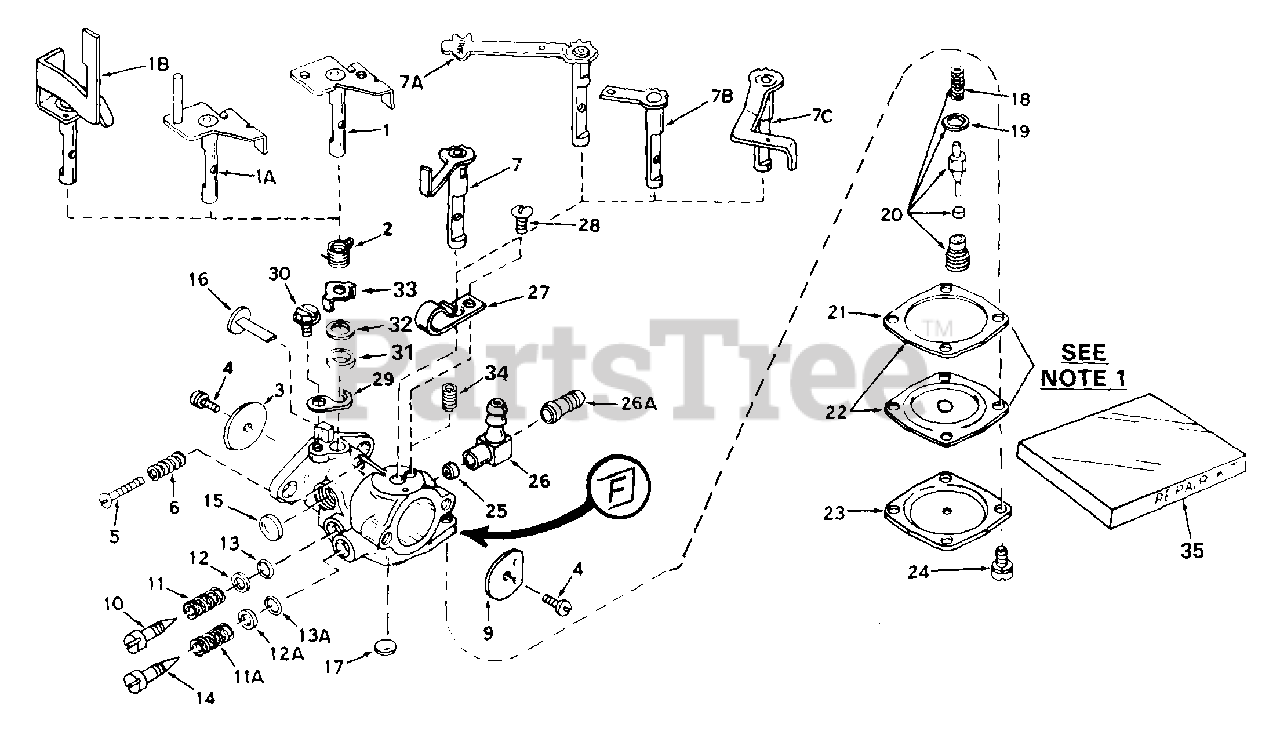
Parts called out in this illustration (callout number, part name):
1	"Shaft & Lever Assy., Throttle
2	Spring, Throttle return
3	Shutter, Throttle
4	Screw, Throttle & Choke shutter
5	Screw, Idle regulating
6	Spring, Idle regulating
7	Shaft & Lever Assy., Choke
9	Shutter, Choke
10	Screw, Idle adj.
11	Spring, Idle adj. screw
11A	Spring, Main adj. screw
12	Washer, Idle adj. screw
12A	Washer, Main adj. screw
13	"O" Ring, Idle adj. screw
13A	"O" Ring, Main adj. screw
14	Screw, Main adj. (.0225 dia. hole)
15	Plug, Welch
16	Element, Pump
17	Plug, Welch
18	Spring, Valve
19	Gasket, Valve seat
20	Inlet Needle, Seat, Gasket & Spring A ssy.
21	Gasket, Diaphragm
22	Diaphragm Assy.
23	Cover, Diaphragm
24	Screw, Cover
25	Valve, Check
26	Fitting, Fuel line
27	Spring, Detent
28	Screw, Detent spring
29	Retainer, Throttle shaft
30	Screw, Retainer
35	Repair Kit
